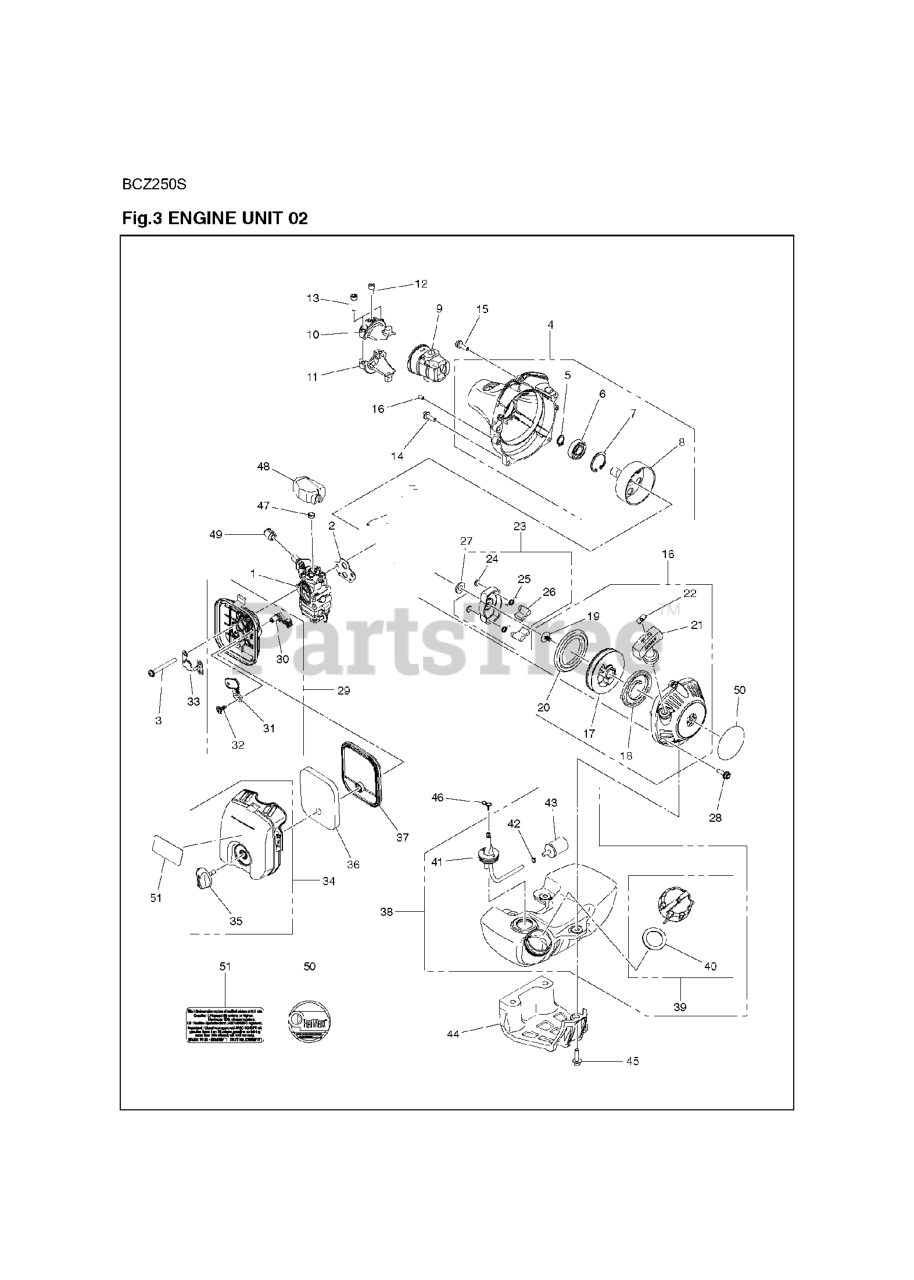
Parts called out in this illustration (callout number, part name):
2	GASKET CARBURETOR
4	HOUSING ASSY
8	CLUTCH DRUM
9	CUSHION UPPER
10	BRACKET UPPER M5X0.8
11	BRACKET LOWER
13	BOLT M5X20 T27
14	BOLT M5 X 16
16	STARTER ASSY
17	STARTER PULLEY
18	SPRING, SPIRAL
19	SCREW
20	ROPE
23	STARTER PULLEY ASSY
27	WASHER T2.0MM
28	BOLT M5 X 16
29	FILTER HOUSING ASSY
31	PLATE
34	COVER ASSY
35	CLEANER KNOB
36	AIR FILTER
38	ASSY TANK EVAP
39	TANK CAP
41	PIPE COMP
42	CLIP
43	FUEL FILTER
44	SKID PLATE
45	BOLT M5X25
46	CLIP
50	DECAL STARTER
51	DECAL , GASOLINE
